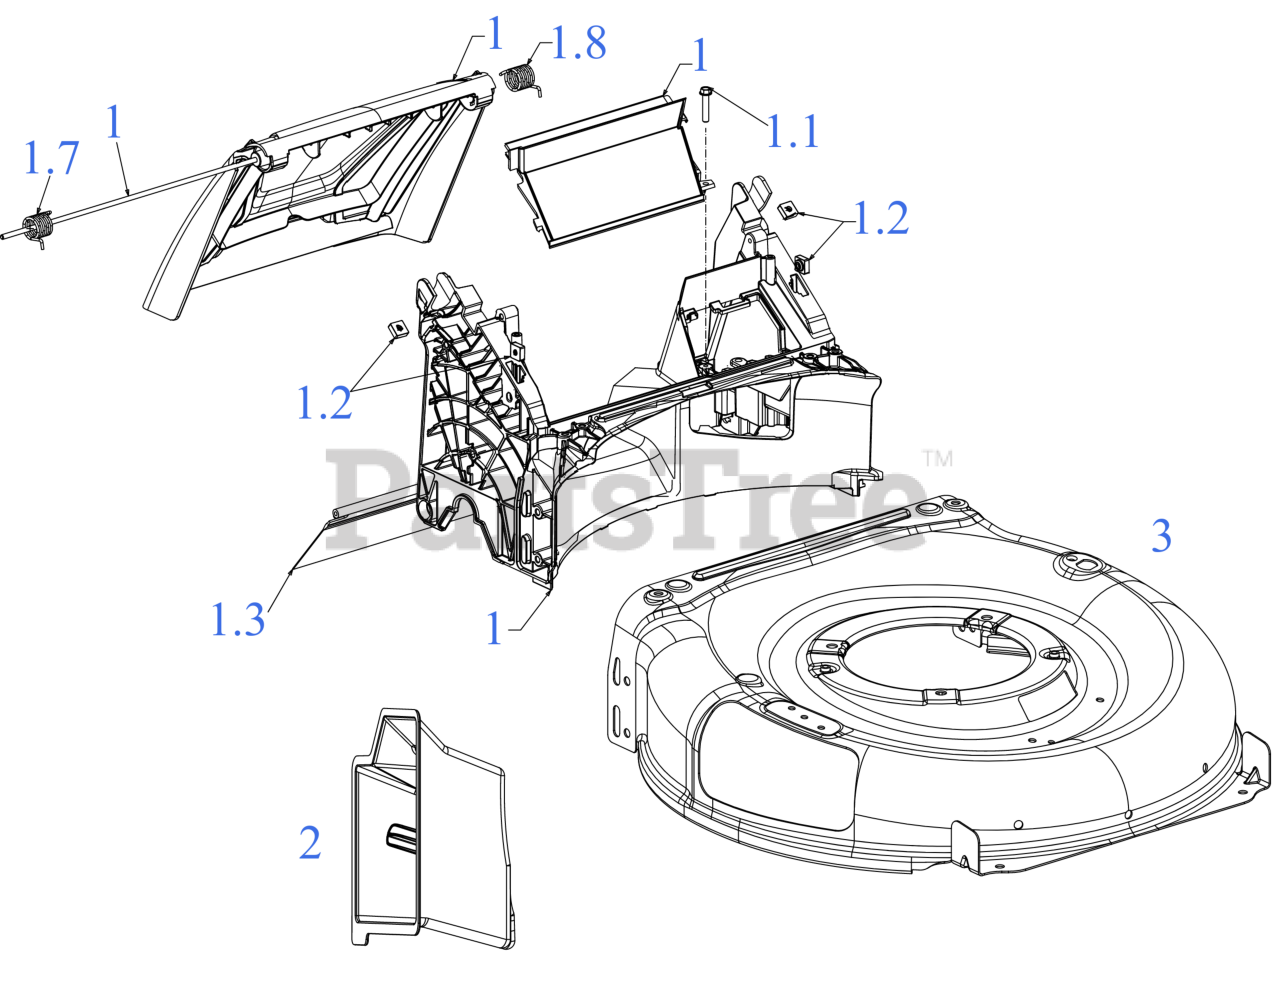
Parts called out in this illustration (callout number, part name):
1	REAR BAFFLE
1.1	SCREW 1/4-15 x 1.250
1.2	SQUARE LOCK NUT 1/4X20
1.3	TRAILSHIELD
1.7	TORSION SPRING (RH)
1.8	TORSION SPRING (LH)
